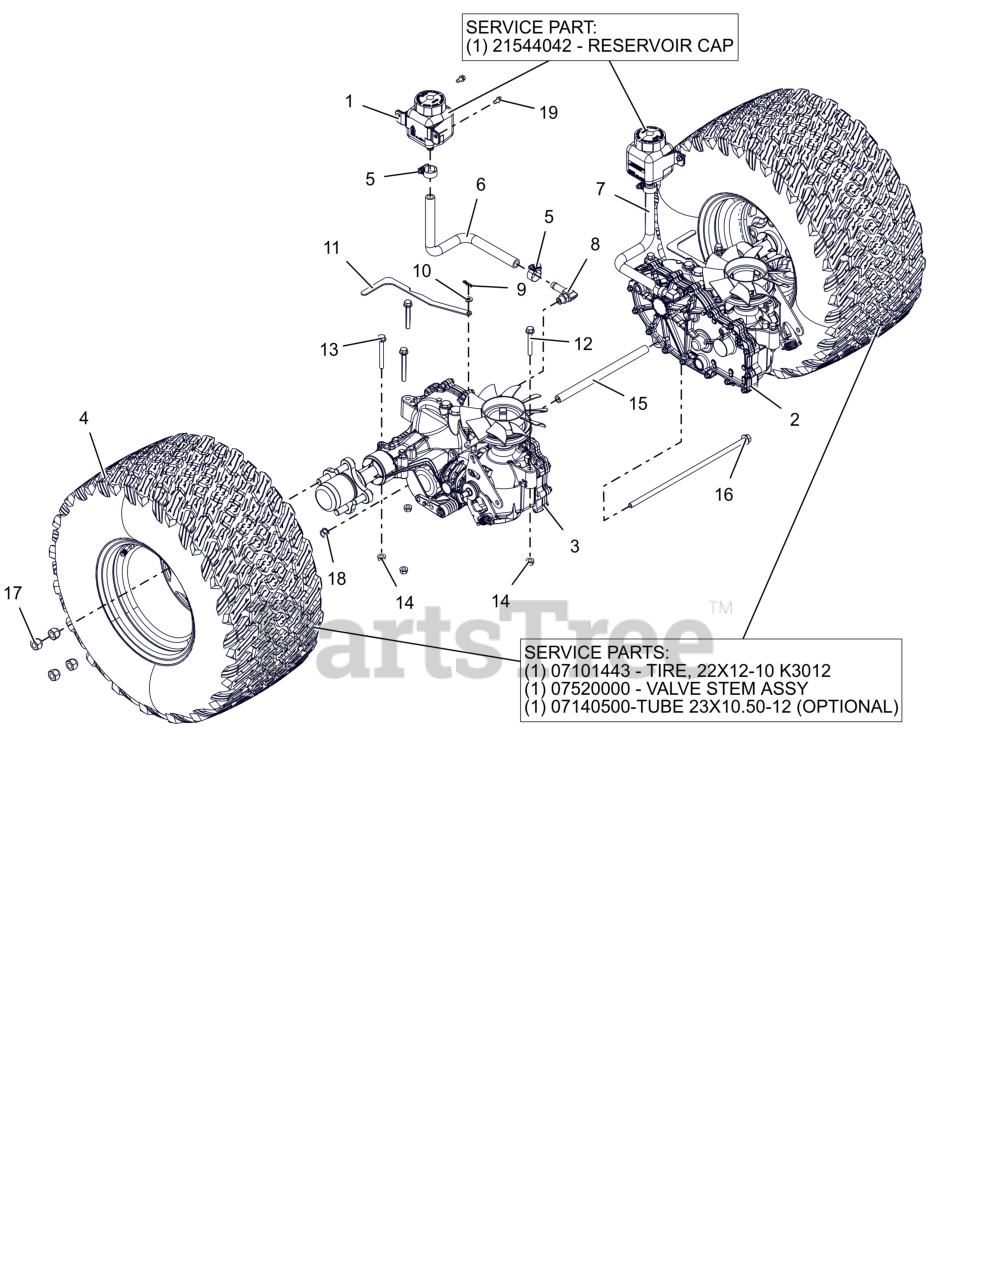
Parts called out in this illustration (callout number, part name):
1	TANK, EXPANSION
1	CAP, HYDRO RESERVOIR REPLAC.
2	TRANSAXLE, ZT3100 - LH
3	TRANSAXLE, ZT3100 - RH
4	ASM, TIRE/WHEEL 22X12-10
4	TIRE, 22X12-10 K3012
4	VALVE STEM ASS'Y
4	TUBE 22,23&24X8.50/9.50/10.00/10.50/12.00-12
5	CLAMP,.88 DIA. HOSE
6	HOSE, FORMED EXPANSION -HD RH
7	HOSE, FORMED EXPANSION -HD LH
8	FITTING, HYD (90 DEG)
9	PIN, HAIR #225 .072X1.09
10	WSHR,FLT .281X.625X.065 ZCC
11	BRKT, VALVE DUM
12	BLT,HEX-FLG .31-18X2.25 G5 ZCC
13	BLT,HEX-FLG .31-18X2.75 G5 ZCC
14	NUT,LK-CTR-FLG .31-18 GF ZCC
15	SPCR, TRANSAXLE .406 ID X .630 OD X 9.95LG (BLACK)
16	BLT, HEX-FLG 0.375-16X13 GR5 ZC120
17	NUT, WHEEL .50-20 ZCC
18	NUT-LK-TOP-FLG .38-16 ZC120
19	SCR-TAP .25-20X.50 HWH ZCC
